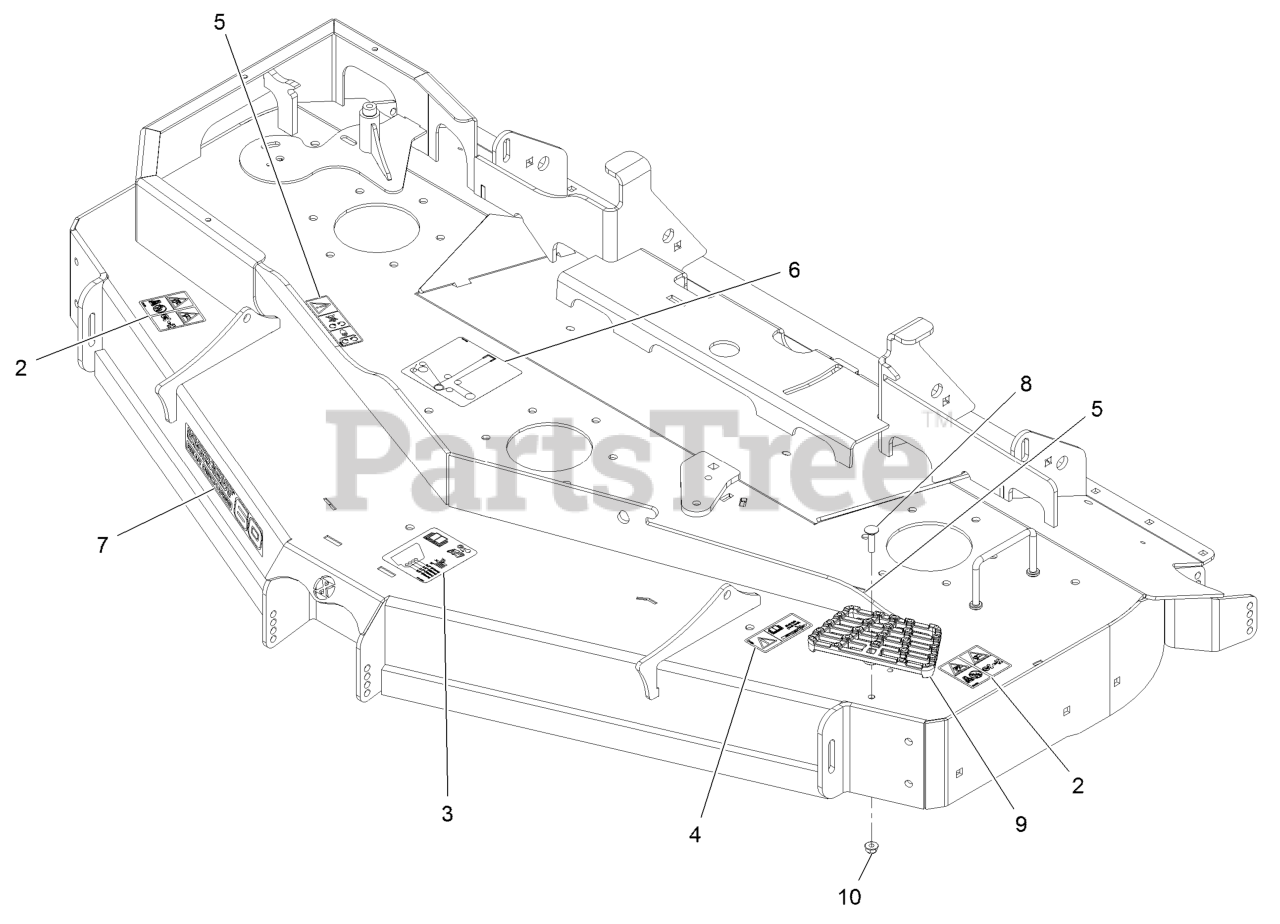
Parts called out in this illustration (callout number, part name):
3	DECAL-ROLLER, ANTI-SCALP
4	DECAL-BOLT TORQUE
5	DECAL-COVER, MISSING
6	DECAL,BELT ROUTING RD DEC
7	Decal, 60Rd
8	Bolt-Carriage 5/16-18 X 1 1/4
9	STEP-DECK
10	NUT-HF, NI
